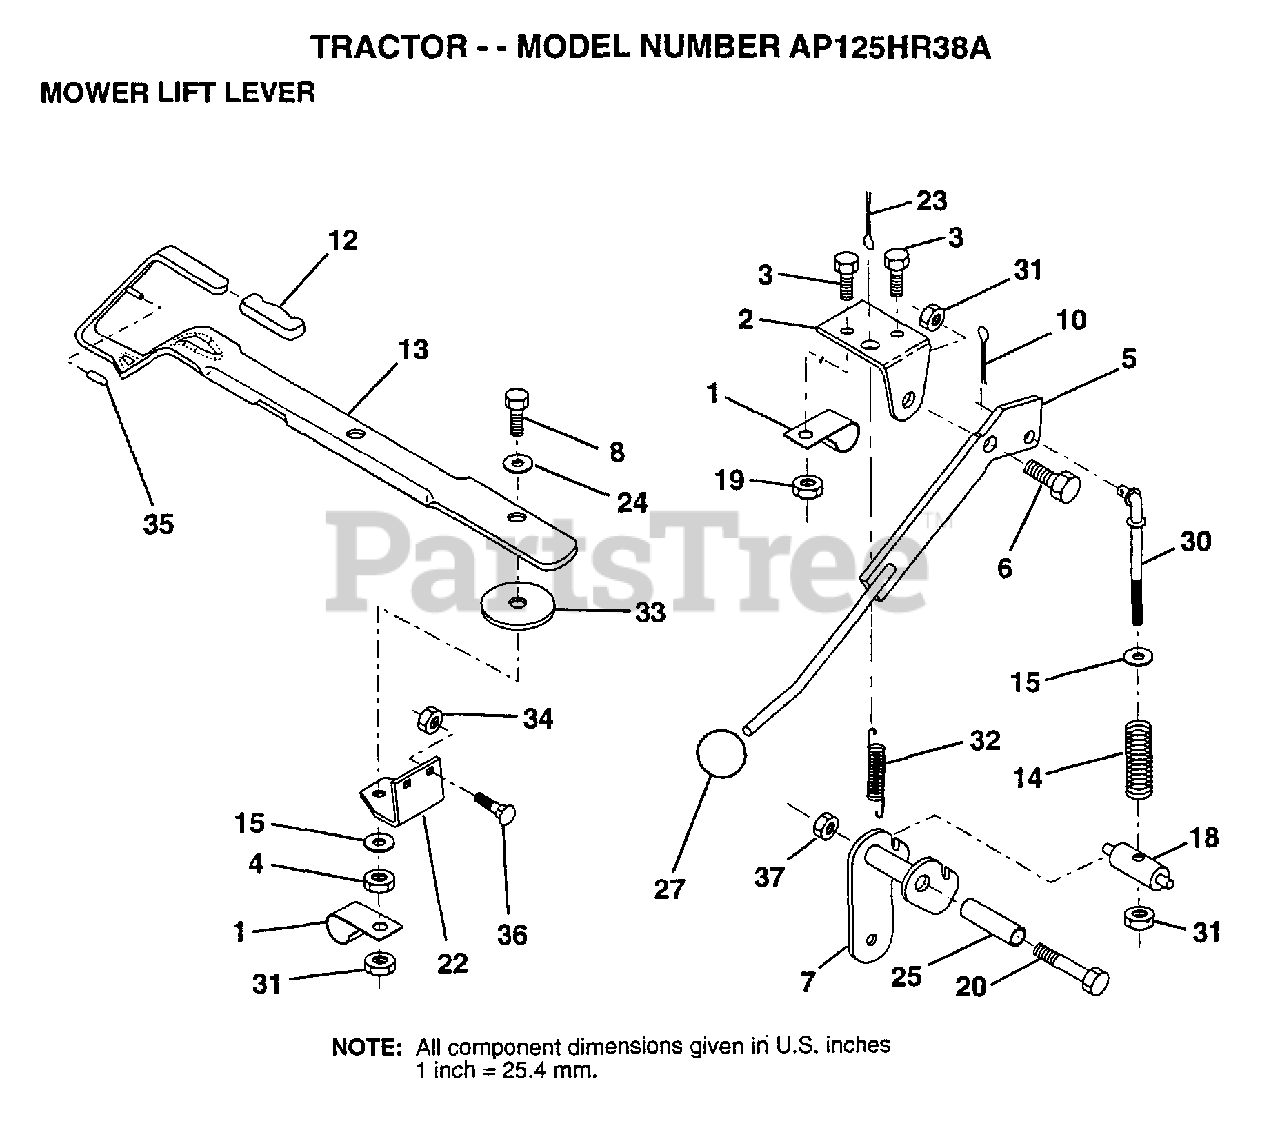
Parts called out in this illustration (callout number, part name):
1	"CLIP,INSULATOR"
2	BRKT CLUTCH
3	BOLT HXHD FIN
4	NUT
5	LEVER.ASM.CLUTCH
6	"BOLT, SHOULDER LT"
7	ARM.CLUTCH.ASM
8	BOLT
10	COTTER PIN
12	GRIP HANDLE
13	LEVER LIFT LR
14	COMP CLUTCH SPRNG
15	WASHER HYT
18	TRUNNION
20	BOLT
22	LIFT LEVER BRKT
24	WASHER
25	TUBE SPACER
27	KNOB
30	ROD TENSION CLUTC
31	LOCKNUT
32	SPRING EXT
33	WASHER
34	NUT
35	VINYL CAP RED
36	BOLT
